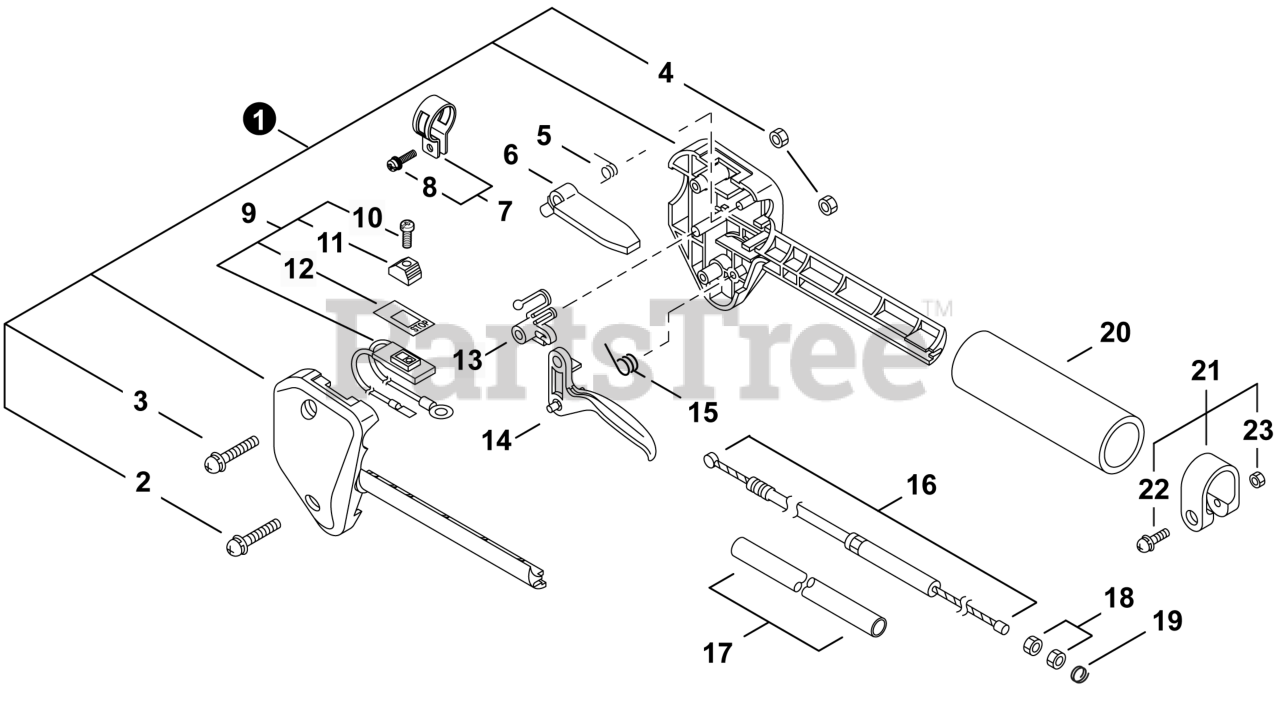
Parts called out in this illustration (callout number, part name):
1	HANDLE KIT, CONTROL
2	SCREW 5x25
3	SCREW 5x35
5	SPRING, TORSION
6	LEVER, THROTTLE LOCKOUT
7	CLAMP KIT
8	SCREW 5x14
9	SWITCH, ON-OFF
10	SCREW 3x10
11	KNOB, SWITCH - ORANGE
12	LABEL - SWITCH
13	LOCKOUT, THROTTLE
14	TRIGGER, THROTTLE
15	SPRING, TORSION
16	CABLE, THROTTLE 320x77.5
17	PIPE, 10x11x180
20	GRIP, HANDLE
21	CLAMP KIT
22	SCREW 5x28
